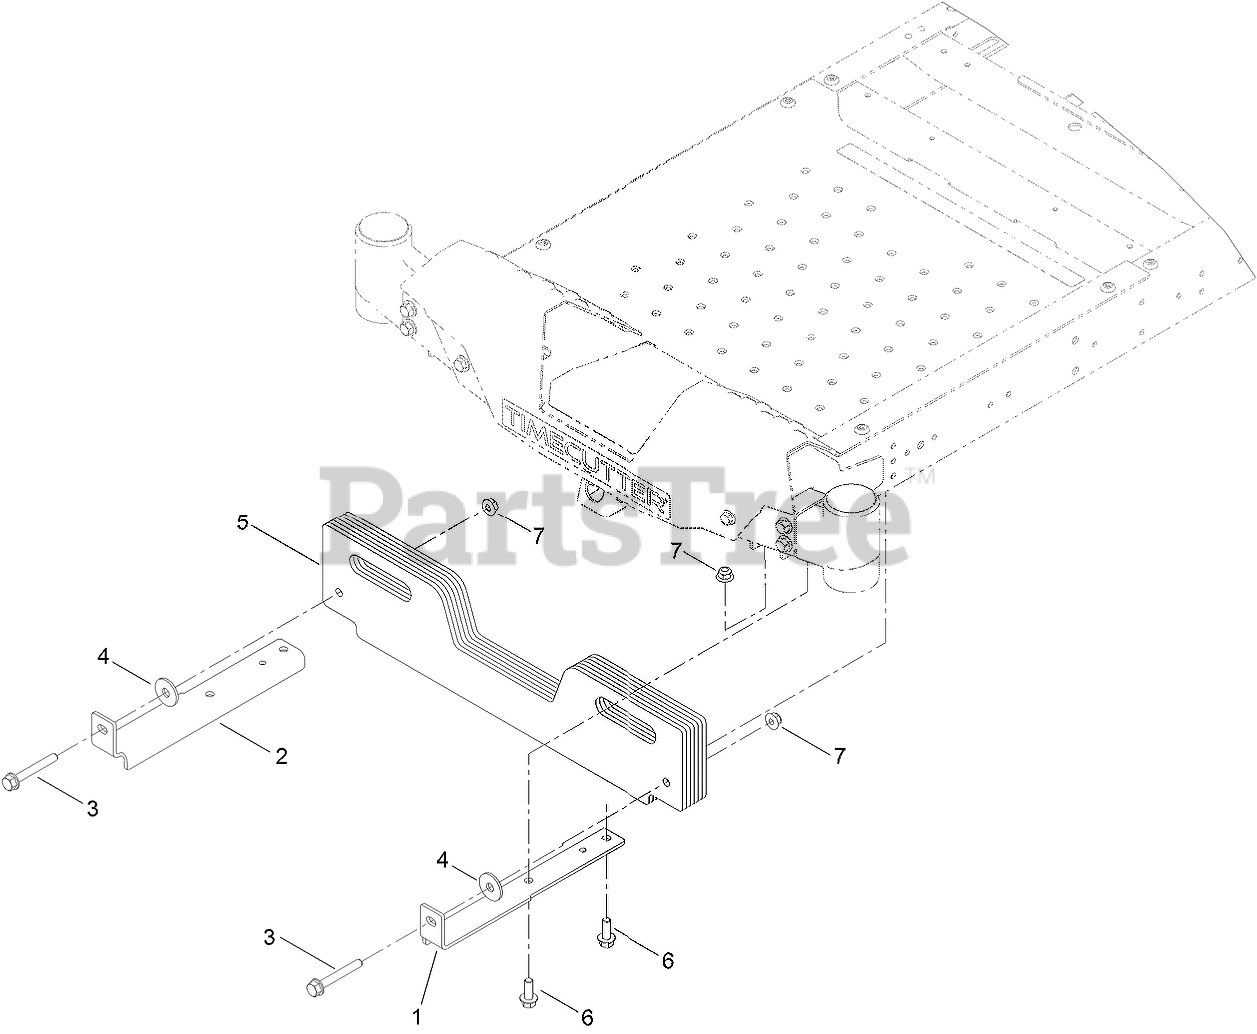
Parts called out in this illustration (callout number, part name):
1	BRACKET-WEIGHT, LH
2	BRACKET-WEIGHT, RH
3	SCREW-SPCL
4	WASHER
5	WEIGHT-BAGGER
6	SCREW-HHF
7	NUT-HF, NI
